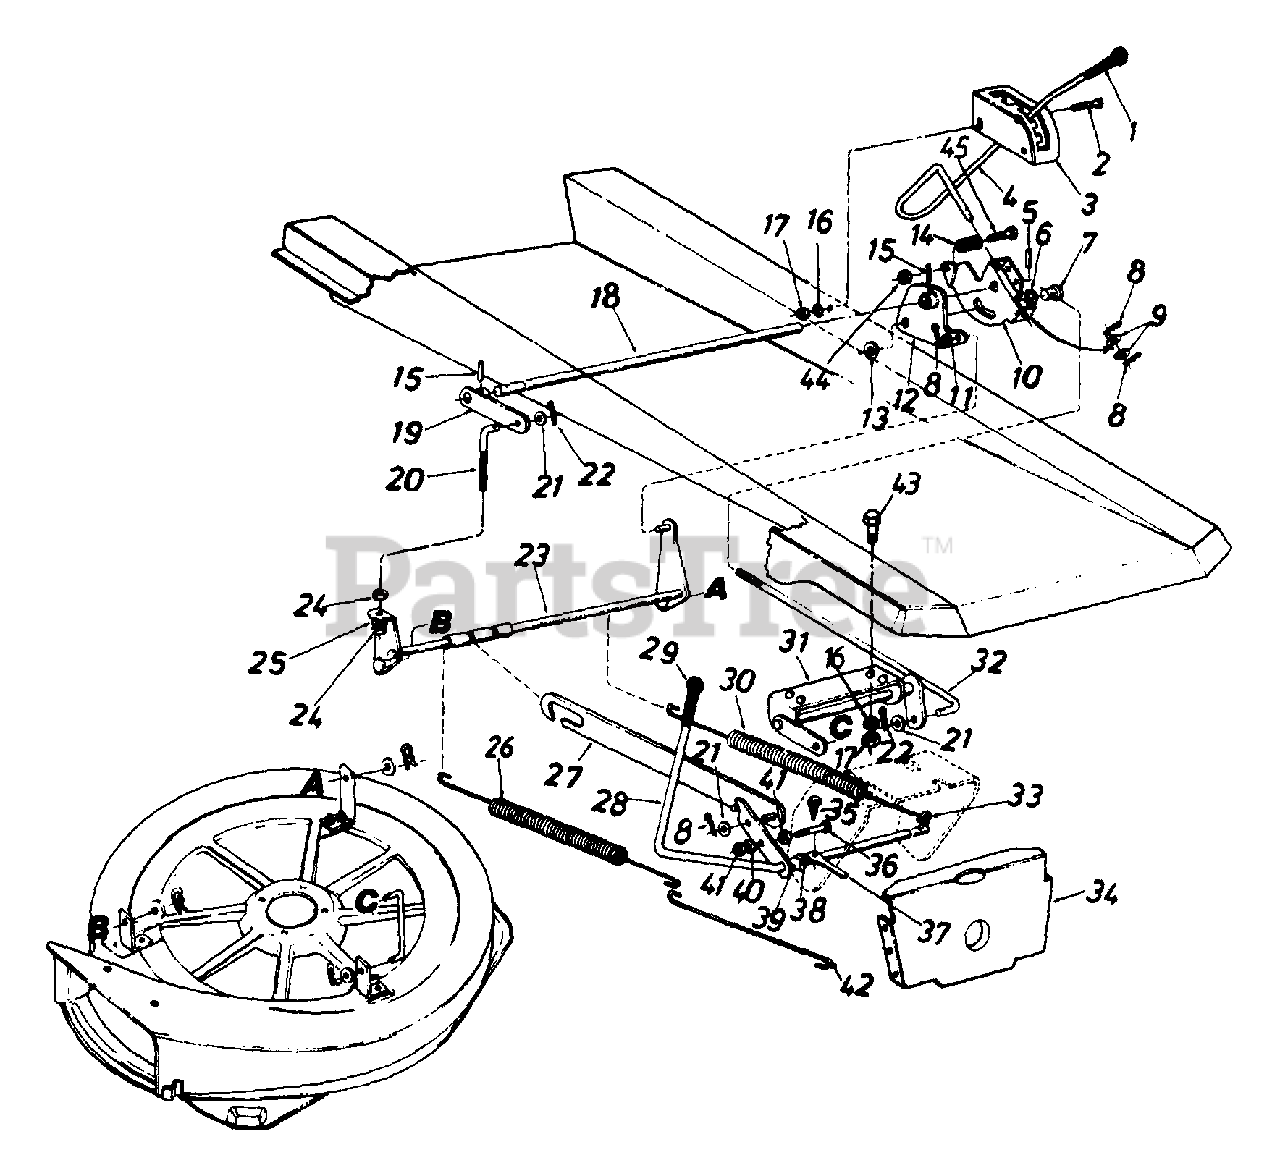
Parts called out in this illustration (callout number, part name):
2	Truss Mach. Scr. 5/16-18 x .75" Lg.
5	Spring Pin Spir. 3/16" Dia. x 1.50" Lg.
6	Fl-Wash..385" I.D. x .87" O.D.
7	Adj. Ferrule Deck Lift Handle
8	Cotter Pin 1/8" Dia. x 1.0"
9	Fl-Wash..531" I.D. x .930" O.D.
12	Deck Lift Brkt. Ass'y. - L.H.
13	Fl-Wash..635" I.D. x 1.04" O.D.
14	Compression Spring .5" Dia. x .9" Lg.
15	Spring Pin Spir. 1/4" Dia. x 1.50" Lg.
16	L-Wash. 5/16" I.D.
17	Hex Nut 5/16-18 Thd.
18	Rear Hgt. Adj. Shaft
19	Deck Lift Brkt. Ass'y. - R.H.
20	Deck Adj. Scr. 3/8-16 Thd.
21	Fl-Wash..385" I.D. x .87" O.D.
22	Intern. Cotter Pin 1/2" Dia.
23	Deck Link Ass'y. - Rear
24	Hex Nut 3/8-16 Thd.
25	L-Wash. 3/8" I.D.
26	Extension Spring 13.84" Lg.
27	Deck Drive Control Bracket
28	Blade Engagement Lever Ass'y.
30	Extension Spring .73" O.D. x 13.84" Lg.
31	Deck Lift Ass'y. - Front
32	Deck Lift Connecting Rod
33	Clevis Pin Special .250" Dia.
36	Hex Bolt 5/16-18 x 1.50" Lg. (Grade 5)
37	Switch Actuator
38	Fl-Wash..531" I.D. x .930" O.D.
39	Spacer .511" I.D. x .70" O.D. x .38" Lg.
40	L-Wash. 5/16" I.D.
41	Hex Nut 5/16-18 Thd.
42	Spring Hook
43	Hex Bolt 5/16-18 x .75" Lg.
44	Hex Cent. L-Nut 1/4-20 Thd.
45	Hex Bolt 1/4-20 x 1.25" Lg.
